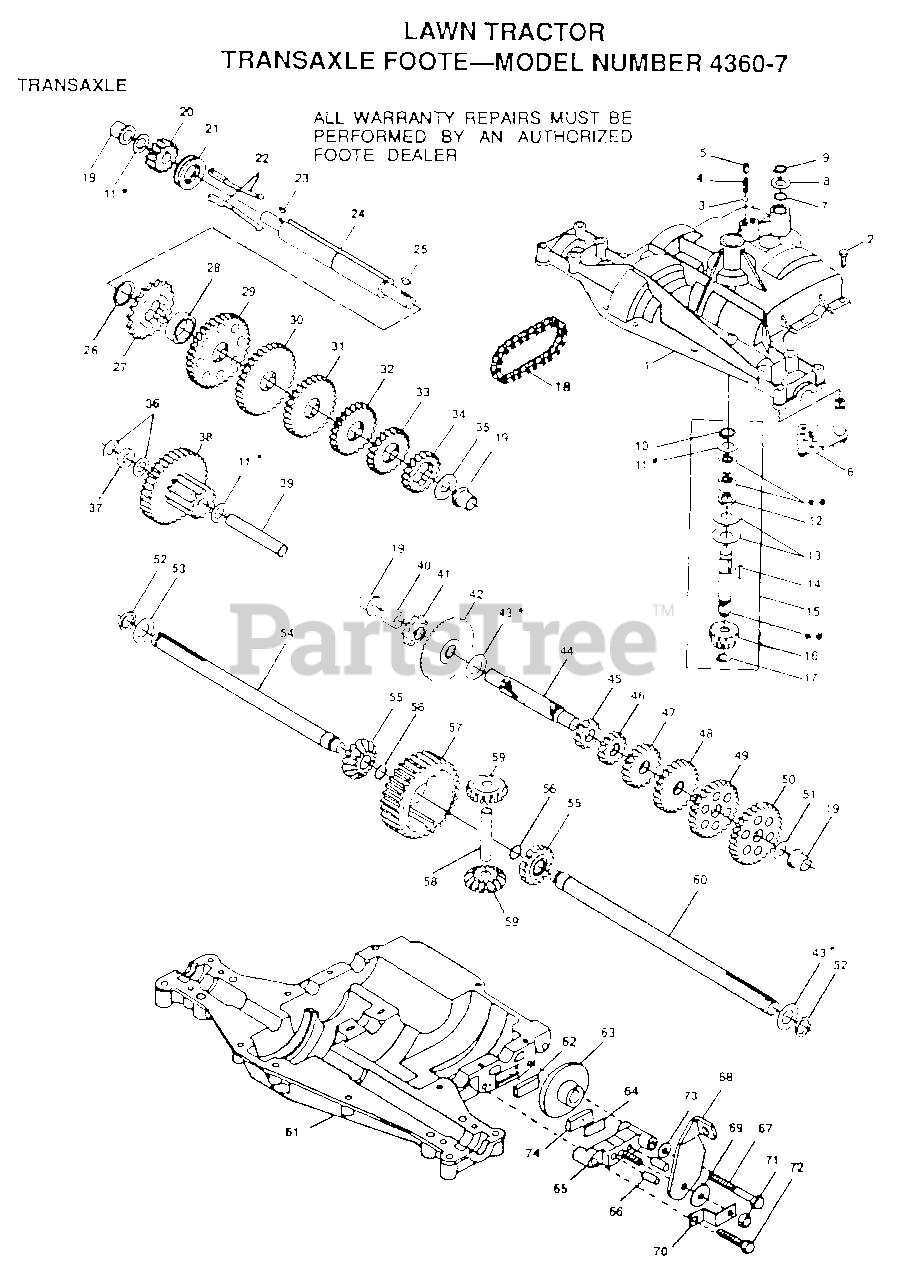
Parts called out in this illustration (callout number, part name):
1	HOUSING UPPER
3	BALL DETENT
4	SPRING, DETENT
5	SCREW, SET
6	ASSY SHIFTER
8	WASHER PLAIN
9	RING RETAINING
10	RING RETAINING
11	WASHER PLAIN
11	WASHER, PLAIN .632 X 1.00 X .026
11	WASHER, PLAIN .632 X 1.00 X .060
13	WASHER, PLAIN .632 X 1.38 X .046
14	KEY WOODRUFF #9
15	ASSY KIT INPUT SHAFT
16	PINION, BEVEL, 14 TEETH
17	RING, RETAINING
18	CHAIN, 24 PITCHES
19	BEARING, FLANGE
20	GEAR SPUR, 14 TEETH
21	COLLAR CLUTCH
22	KEY CLUTCH
23	KEY WOODRUFF #3
24	SHAFT INTERMEDIATE
25	KEY, WOODRUFF, #61
26	RING, RETAINING
27	SPROCKET, 18 TEETH
29	GEAR, SPUR, 37 TEETH
30	GEAR, SPUR, 35 TEETH
31	GEAR, SPUR, 30 TEETH
32	GEAR, SPUR, 25 TEETH
33	GEAR, SPUR, 22 TEETH
35	WASHER, PLAIN .640 X 1.37 X .061
36	WASHER, PLAIN .632 X 1.00 X .026
37	SPACER .630 X 1.00 X .169
38	ASSY GEAR COMB 12&35 TEETH
39	SHAFT IDLER
40	SPACER .635 X .875 X .755
41	SPROCKET, 9 TEETH
42	GEAR, BEVEL, 42 TEETH
43	WASHER PLAIN
43	WASHER, PLAIN .758 X 1.25 X .031
44	SHAFT, DRIVE
45	GEAR, SPUR, 12 TEETH
46	GEAR SPUR, 15 TEETH
47	GEAR, SPUR, 20 TEETH
48	GEAR, SPUR, 25 TEETH
49	GEAR, SPUR, 28 TEETH
50	GEAR, SPUR, 31 TEETH
51	WASHER, PLAIN .632 X 1.00 X .060
53	WASHER PLAIN
54	AXLE LEFT HAND
55	GEAR, MITER, 15 TEETH
56	RING, RETAINING
57	GEAR, SPUR, 32 TEETH
58	SHAFT, CROSS
59	GEAR, MITER, 15 TEETH
60	AXLE, R.H.
61	HOUSING LOWER
62	PUCK, FRICTION
63	DISC, BRAKE
65	JAW, BRAKE
66	PIN, DOWEL
67	SCREW TAPPING
68	LEVER, ACTUATING
69	WASHER, PLAIN .321 X 1.00 X .055
70	BRACKET, ANTI-ROTATION
71	LOCKNUT 5/16-24
72	SCREW TAPPING
73	WASHER PLAIN
74	PUCK, FRICTION
